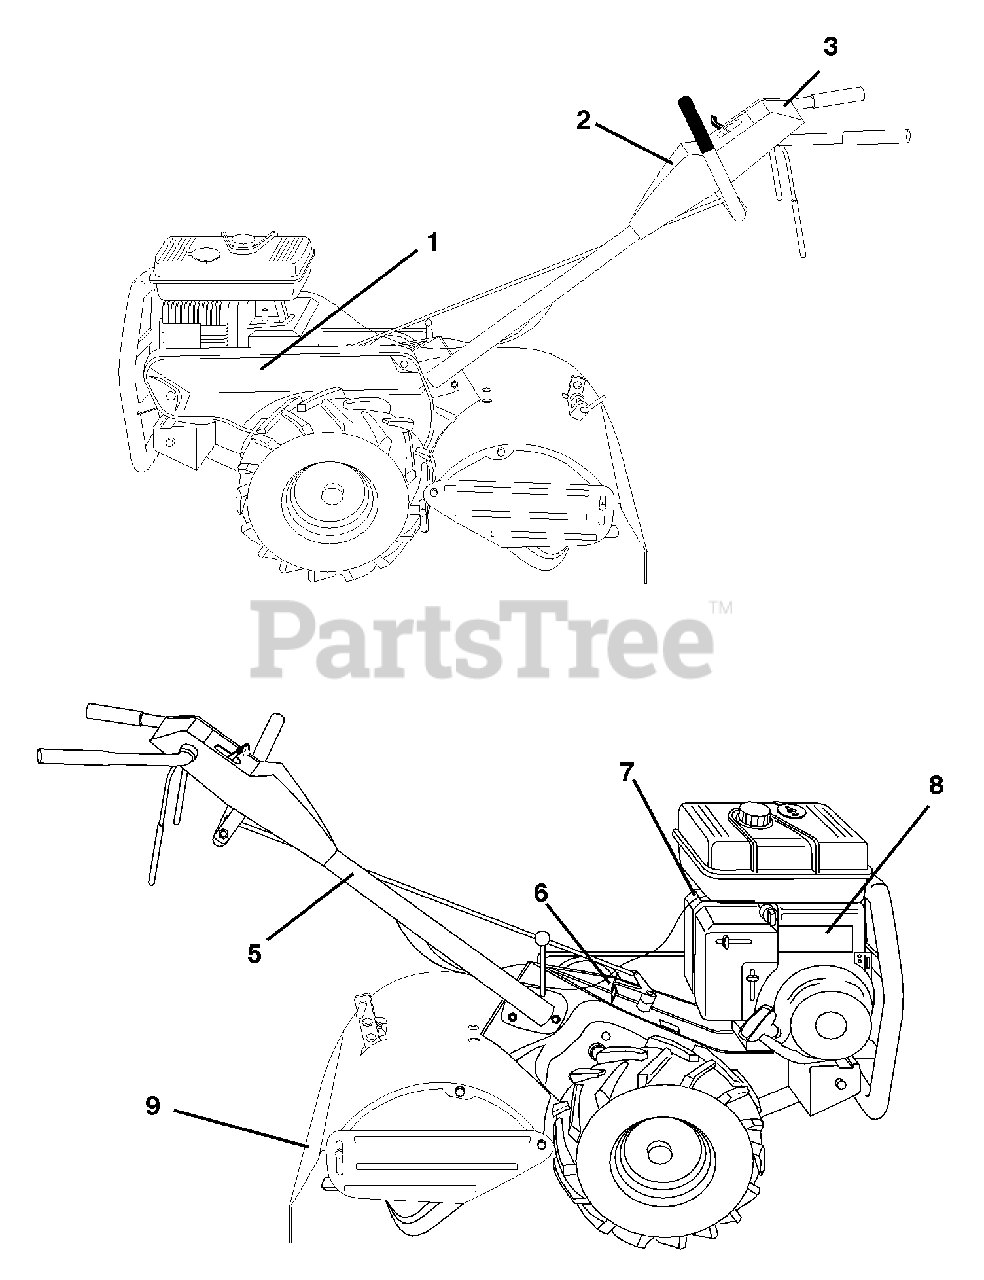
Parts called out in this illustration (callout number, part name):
1	Decal, Logo
2	Decal, Logo
3	Decal, Logo
5	Decal, Hand Placement
6	Decal, Shift Indicator
7	Decal, Caution
8	Decal, Briggs & Stratton
9	Decal, Warning, Rotating Tines
